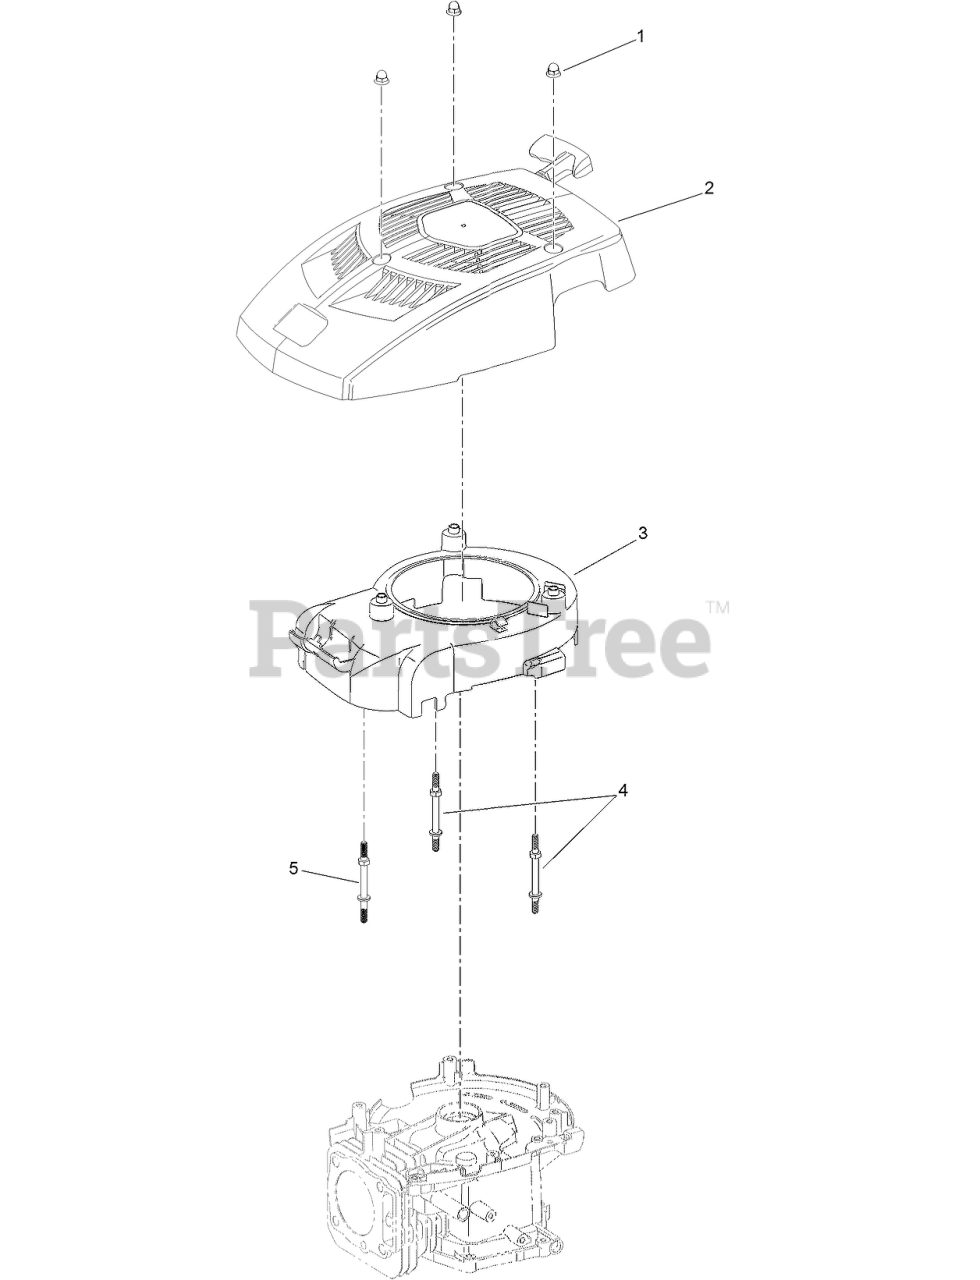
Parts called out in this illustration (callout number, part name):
1	NUT-ACORN
2	RECOIL SHROUD ASM
3	SHROUD-FAN
4	STUD-SHROUD
5	STUD-SHROUD
